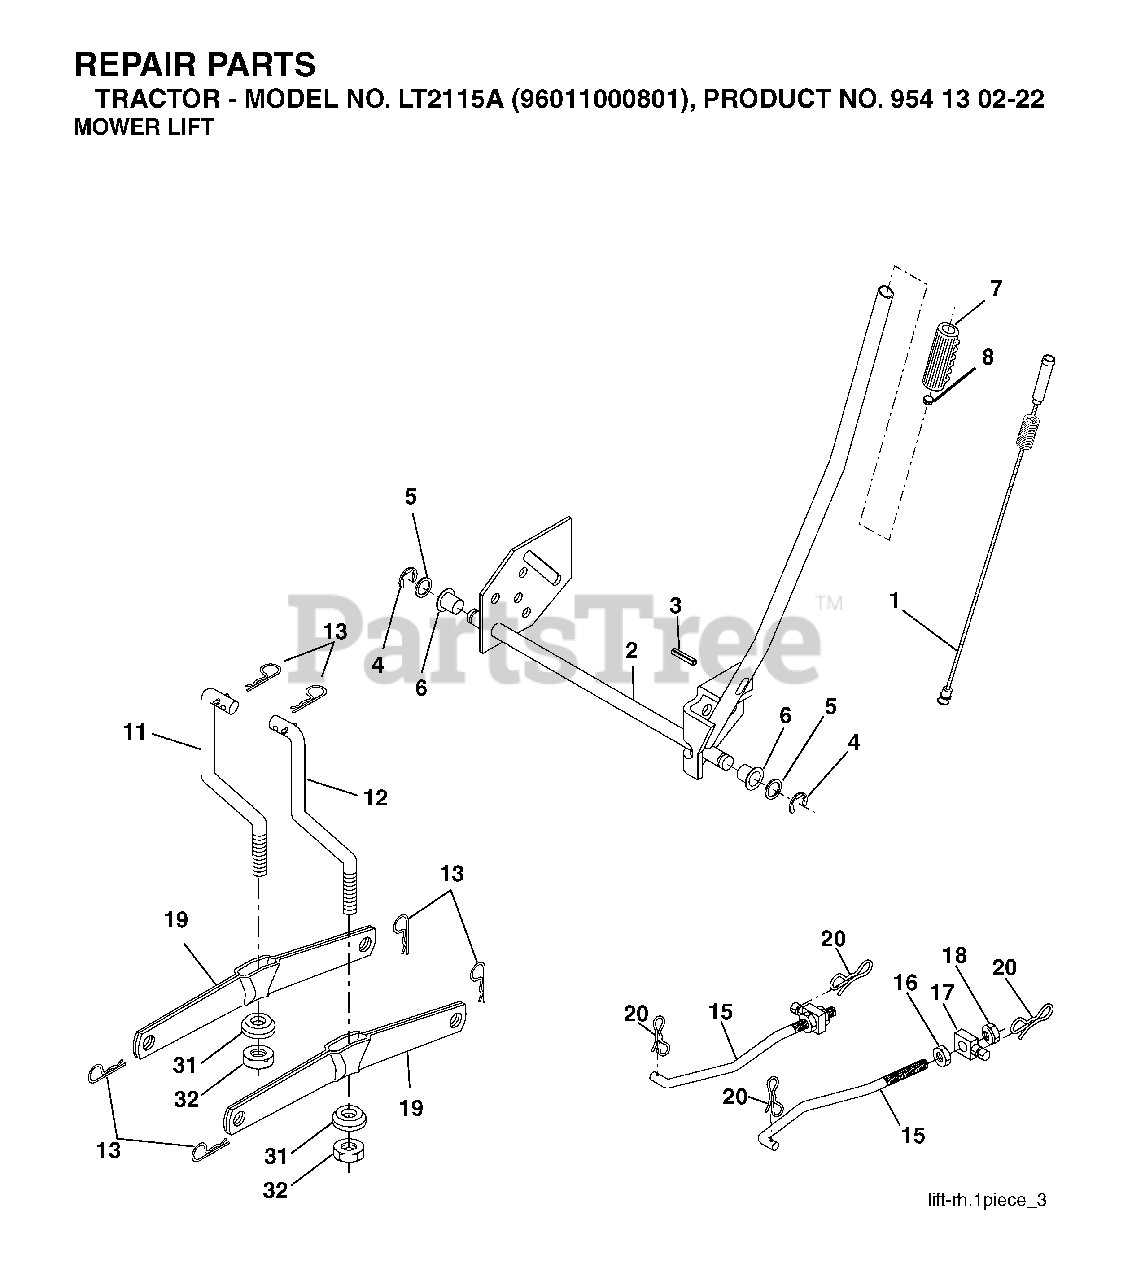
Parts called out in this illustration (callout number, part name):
4	RETAINING RING LT
6	BEARING.NYLON
7	GRIP
11	LINK LIFT LH
12	LINK LIFT RH
13	RETAINER-SPRNG RB
15	LINK.SUSPENSION.FRONT
16	NUT
18	NUT
19	ARM.REAR.SUSPENSION
20	PIN.COTTER.7/16.BOW TI
31	BEARING.PIVOT.LIFT
32	NUT CROWNLOCK 3/8-24
